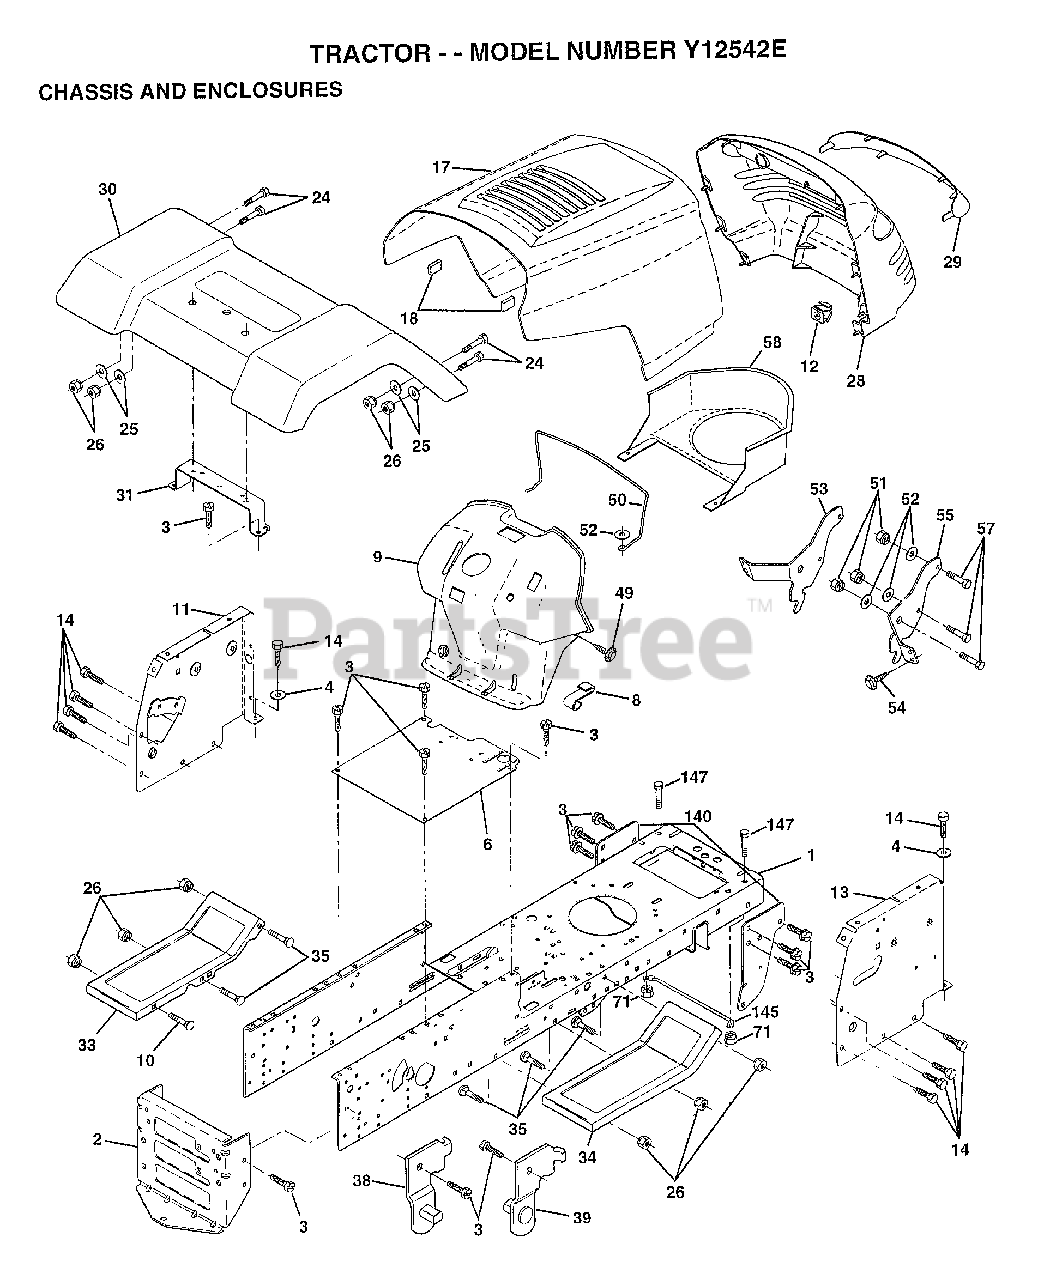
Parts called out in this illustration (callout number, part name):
1	CHASSIS ASM
3	SCREW
4	WASHER
6	SADDLE
8	CLIP.RETAINER
9	DASH PRIVATE LABEL
11	PANEL DASH LH
12	CLIP.TINNERMAN
13	"PANEL DASH,RH"
14	SCREW LT
17	HOOD.STEEL.ASSY
24	BOLT
25	WASHER
26	NUT
28	GRILLE-MS428
29	LENS GRILLE
30	FENDER
31	BRKT FENDER
33	FOOTREST.LH.LT/GT
34	FOOTREST.RH.LT/GT
35	BOLT
38	BRACKET ASM LH
39	BRACKET ASM RH
49	SCREW HEX CRT
50	"ROD SUPPORT,DASH"
51	NUT
52	WASHER
53	BRACKET.GRILLE.LH
55	BRACKET.GRILLE.RH
58	AIR DUCT
140	BRKT SUSPENSION
145	"ROD POVOT,CHASSIS"
147	BOLT LT
